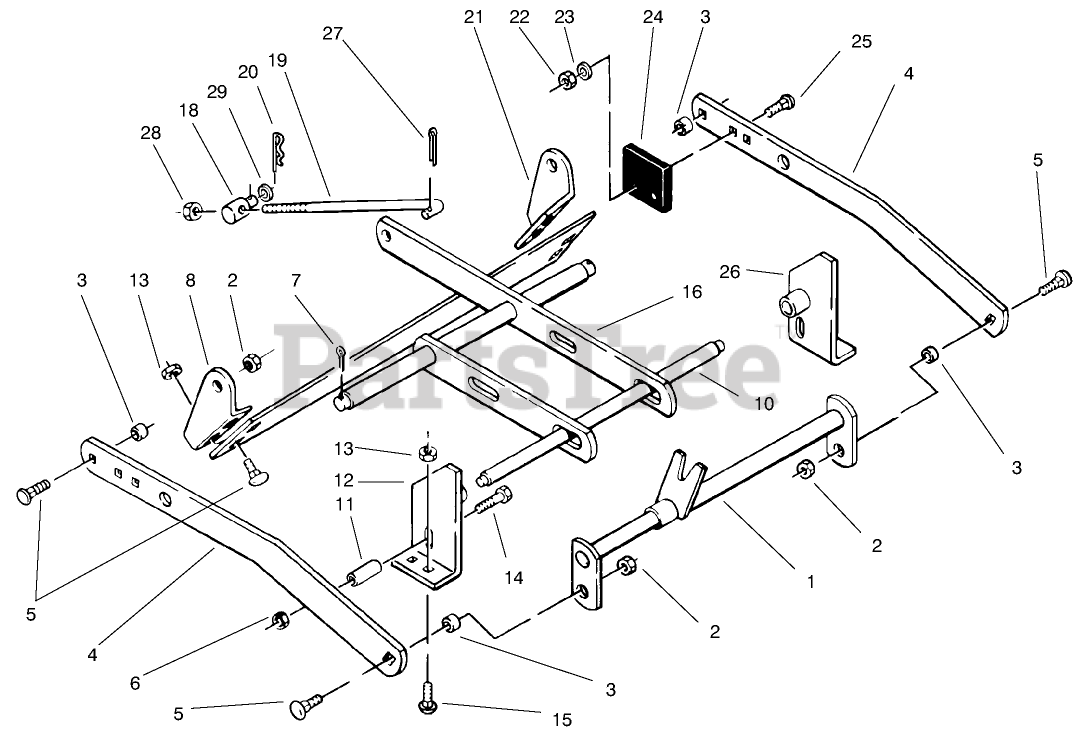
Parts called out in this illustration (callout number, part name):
1	Hitch
2	LOCKNUT-FLANGE
3	SPACER
4	Bar Draft
5	BOLT-CARR
6	NUT-LOCK, NI
7	PIN-COTTER
8	Bracket-Rt. Rear
10	Front Shaft
11	SPACER
12	Bracket-R.H.
13	NUT-LOCK, NI
14	BOLT-CARR
15	BOLT-CARR
16	Leveler
18	TRUNNION
19	LIFT ROD
20	PIN-HAIR
21	Bracket-L.H. Rear
22	NUT-LOCK, NI
23	WASHER-FLAT
24	BUMPER
25	SCREW-CARR
26	Bracket-L.H.
27	PIN-COTTER
28	NUT-LOCK, NI
29	WASHER-FLAT
